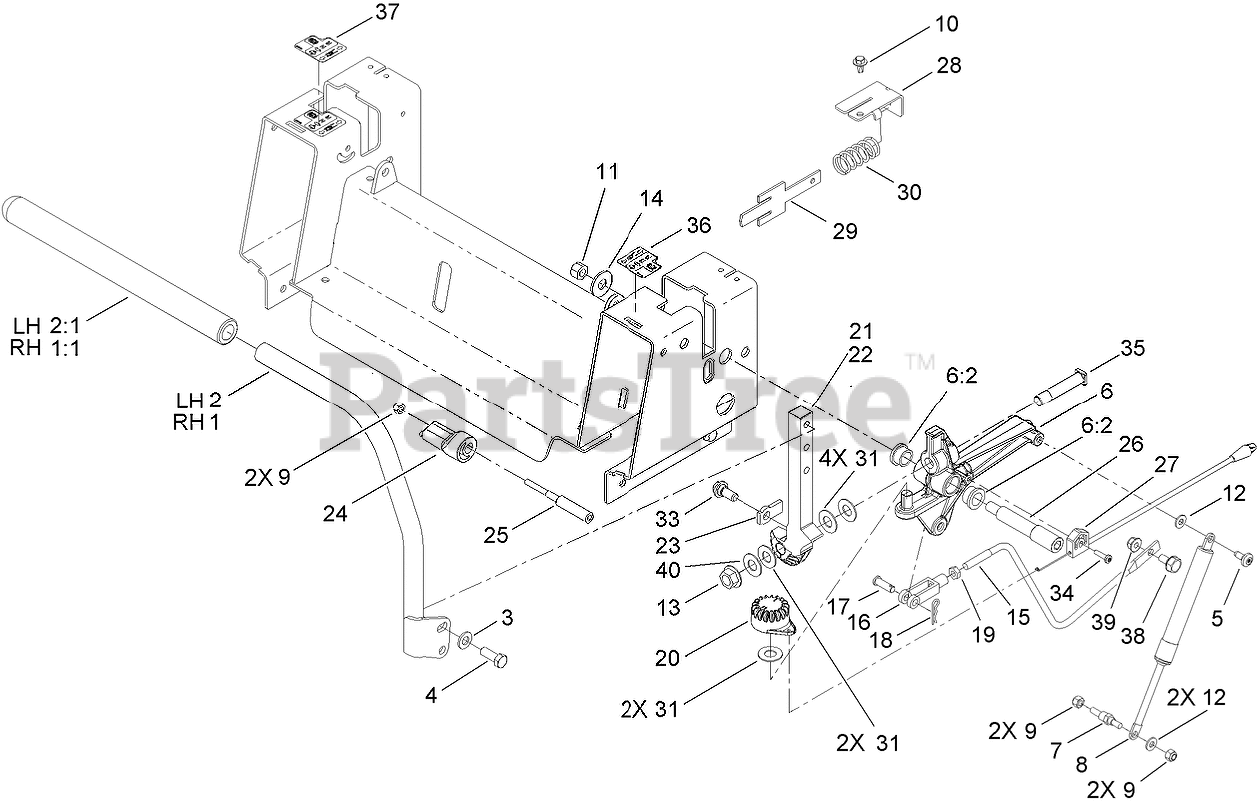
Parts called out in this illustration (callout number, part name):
2	LH HANDLE ASM
3	WASHER-FLAT
4	SCREW-HH
5	SCREW-SHOULDER
6	ACTIVATOR ARM ASM
6:2	BUSHING
7	STUD-DAMPER
8	Damper-Control, Motion
9	NUT-LOCK, NI
10	SCREW-HHFTF
11	NUT-LOCK, NI
12	WASHER-FLAT
13	NUT-HF
14	WASHER-FLAT
15	LINK-HYDRO
16	YOKE-ADJUSTABLE
17	PIN-CLEVIS
18	PIN-COTTER
19	NUT-JAM
20	GEAR-CONTROL
21	ARM-ACTUATOR, LH
23	TAB-STOP
24	ECCENTRIC
25	SCREW-ECCENTRIC
26	BOLT-SHOULDER
27	CABLE-BRAKE, PARKING
28	BRACKET-RETURN
29	PLATE-RETURN
30	SPRING-COMPRESSION
31	WASHER-PIVOT
33	SCREW-HH
34	SCREW-TORX
35	BOLT-SHOULDER
36	DECAL-CONTROL LEVER, LH
37	DECAL-CONTROL LEVER, RH
38	BOLT-SHOULDER
39	NUT-HF, NI
40	WASHER-TEFLON
